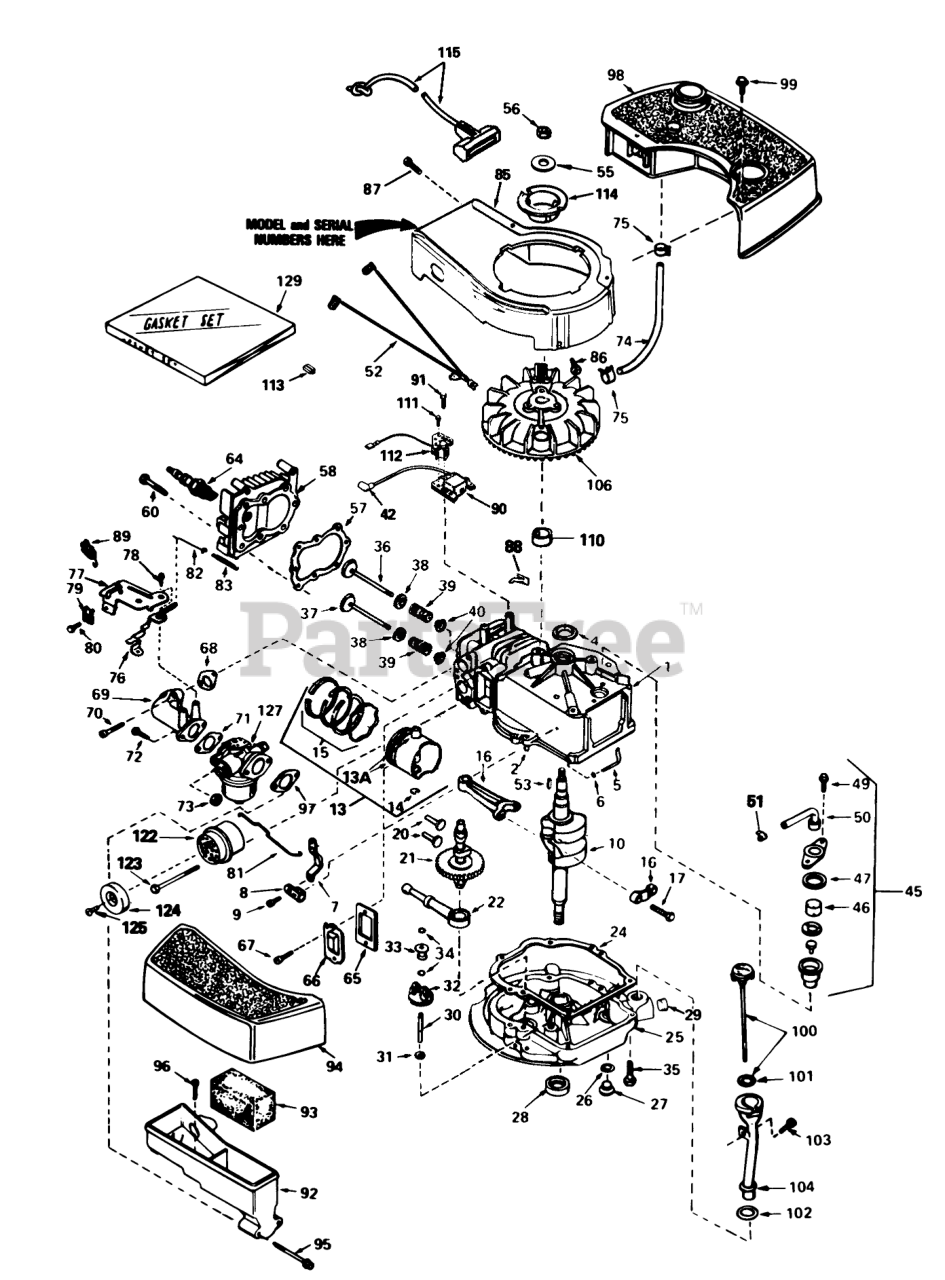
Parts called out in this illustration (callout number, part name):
1	Cylinder Assy. (Incl. #2 & 4)
2	Pin-Dowel
4	Seal-Oil
5	Rod, Governor (Incl. #6)
6	Washer-Flat
7	Governor Lever
8	Clamp-Lever, Governor
9	Screw
10	Crankshaft
13	Piston, Pin & Ring Assy. (Std.)(Incl. #13A, 14 & 15)
13	Piston, Pin & Ring assy. (.010 oversize)(Incl. #13A, 14 & 15)
13	Piston, Pin & Ring Assy. (.020 oversize)(Incl. #13A, 14 & 15)
13A	Piston & Pin Assy. (Std.)(Incl. #14)
13A	Piston & Pin Assy. (.010 over size)(Incl. #14)
13A	Piston & Pin Assy. (.020 over size)(Incl. #14)
14	Ring-Retaining, Piston Pin
15	Ring Set (Std.)
15	Ring Set (.020" OS)
15	Ring Set (.010" OS)
16	Rod Assy., Connecting (Incl. #17)
17	Bolt-Rod, Connecting
20	Lifter-Valve
21	Camshaft(Mech.Comp. Release)
22	Oil Pump ASM
24	Gasket, Mounting
25	Flange Assy., Mounting (Incl. #26 thru 30)
26	Gasket-Oil Drain
27	Plug Oil Drain
28	Seal Oil
29	Plug-Pipe
30	Shaft-Governor
31	Washer-Flat
32	Gear Assy., Governor (Incl. #31)
33	Spool-Governor
34	Ring-Retaining
35	Screw (1/4-20 x 1-1/4)
36	Valve, Intake (Std.)(Incl. #40)
36	Valve, Intake (1/32" oversize)(Incl. #40)
37	Valve, Exhaust (Std.)(Incl. #40)
37	Valve Exhaust (1/32" over size)(Incl. #40)
38	Cap-Upper Valve Spring
39	Spring-Valve
40	Cap-Valve, Spring
42	Cover-Spark Plug
45	Breather Assy. (Incl. #46 thru 51)
46	Element-Breather
47	Gasket-Breather
49	Screw (10-24 x 9/16)
50	Tube, Breaker
51	Clip, Breather
52	Wire-Ground
53	Key-Flywheel
55	Washer-Belleville
56	Nut-Flywheel
57	63573 GIL 42 SNWTHW
58	Head-Cylinder
60	Screw (5/16-18x1-1/2)
64	Plug, Spark (Autolite 458, Champion J-19LM or equiv.)
65	Gasket-Breather
66	Cover-Valve
68	Gasket-Intake
69	Pipe, Intake (Incl. #68)
70	Screw (1/4-20 x 1)
71	Gasket-Carburetor
72	Screw (1/4-28 x 7/8)
73	Nut and Lock Washer (1/4-28)
74	Line-Fuel
75	Clamp-Line, Fuel
76	Lever Control
77	Control Assy., Speed (Incl. #76, 78 & 89)
78	Screw, Hex Washer Hd Shoulder Self-Tap
79	Conduit
80	Screw (10-32 x 3/8)
81	Link-Throttle
82	Link Governor Spring
83	Spring Governor
85	Housing, Blower
86	Screw (1/4-20x19/32)
87	Screw (10-24 x 9/16)
88	Clip-Wire
89	Terminal
90	Solid State
91	Screw
92	Body Air Cleaner
93	Filer, Air
94	Cove, Air Cleaner
95	Screw Fil Hd.
96	Screw, Hex Washer Hd Shoulder Self-Tap
97	Gasket-Air Cleaner
98	Tank-Fuel
99	Screw (10-32 x 35/64)
100	Dipstick, Oil (Incl. #101)
103	Screw (10-32 x 1/2)
104	Tube-Oil Fill
106	Flywheel
111	Screw (8-32x27/64)
112	Coil, Alternator
113	Terminal
114	Hub-Starter
115	Rope Assy., Starter
122	Muffler (Incl. #123)
124	Cover-Muffler
125	Screw
127	Carburetor (Incl. #71)
129	Gasket Set
